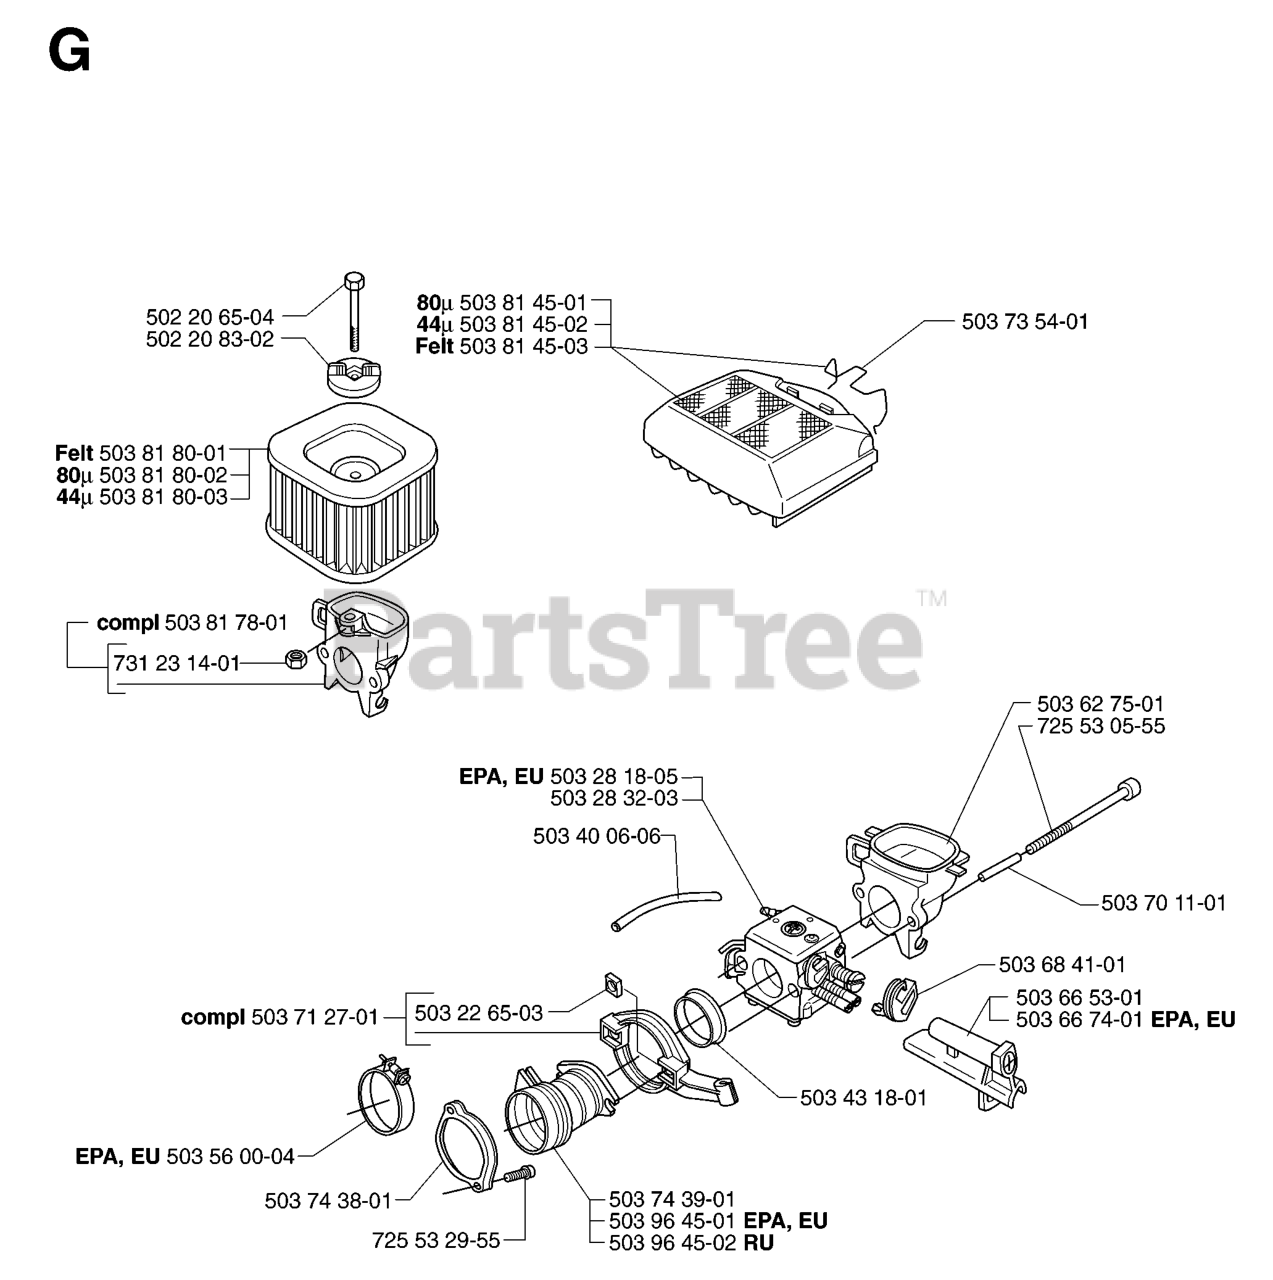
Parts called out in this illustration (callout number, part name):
1	LEVER.CONTROL.SPEED/DEFLEC.BLK
2	LEVER.CONTROL.CHUTE.ROTATON.BL
3	BOLT SHOULDER_HEX
4	SPRING.COMPRESSION.82LBS
5	NUT HEX_LRG FLG_1_4-20_LOCK
6	BRACE.SUPPORT.SPEED.BLACK
7	WASHER.FLAT.625 X .375 NYLON
